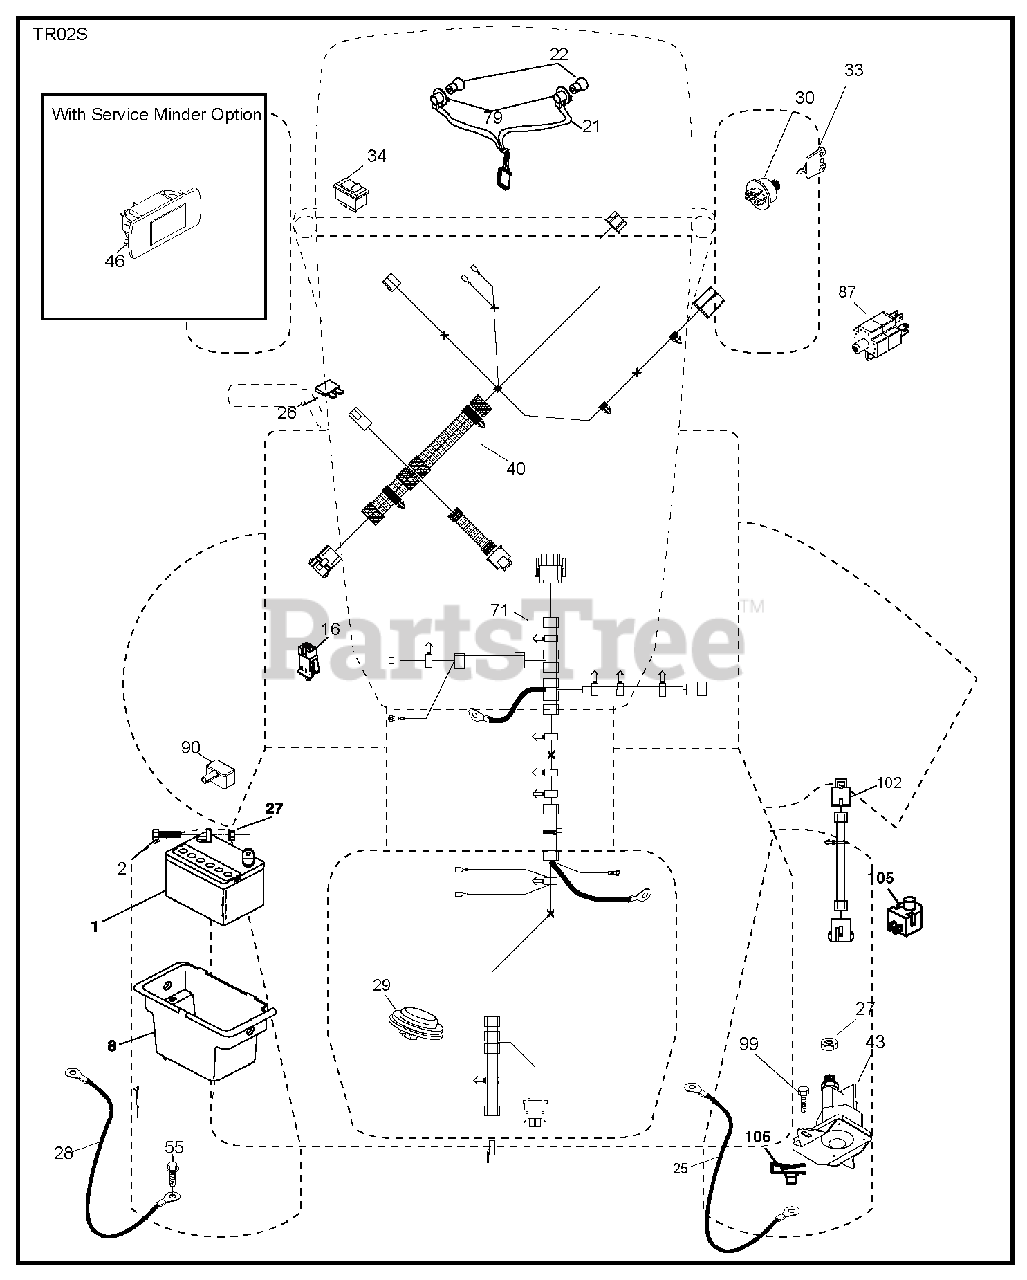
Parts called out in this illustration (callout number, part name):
1	REPL BY 532 12 38-99
2	BOLT.HEX.1/4.X.3/4.DICHROMATE
8	BOX.BATTERY.MNT.REAR.L
16	SWITCH INTERLOOK PUSH-IN
21	HARNESS.LIGHT W/4152J BULBS
22	LIGHTBULB
25	CABLE.BATT.RED.8GA.17
26	FUSE 20AMP
27	NUT
28	CABLE.GROUND.REAR.BATTERY.8G
29	SWITCH.SEAT.DELTA.OPC.
30	SWITCH.IGN.DELTA.W.LGH.ROS
33	KEY.CHAIN.BLISTER.PACK.GEN.USA
34	SWITCH LT
40	HARNESS.TEX.DASH.MAN.REAR BATT
43	SOLENOID.W/BRASS.PLUNGER
55	SCREW 5/16"
71	HARNESS.TEX.CHSSIS.REAR.BATT
79	BULB HOLDER ASM.
87	SWITCH.INTRLCK.CLUTCH.
90	COVER.TERMINAL.BATTERY
99	SCREW HEXWSHR 1/4-20X3/4
102	HARNESS.PIGTAIL.VARIATOR.SD
105	REVERSE SWITCH
106	1/4-20 U NUT
